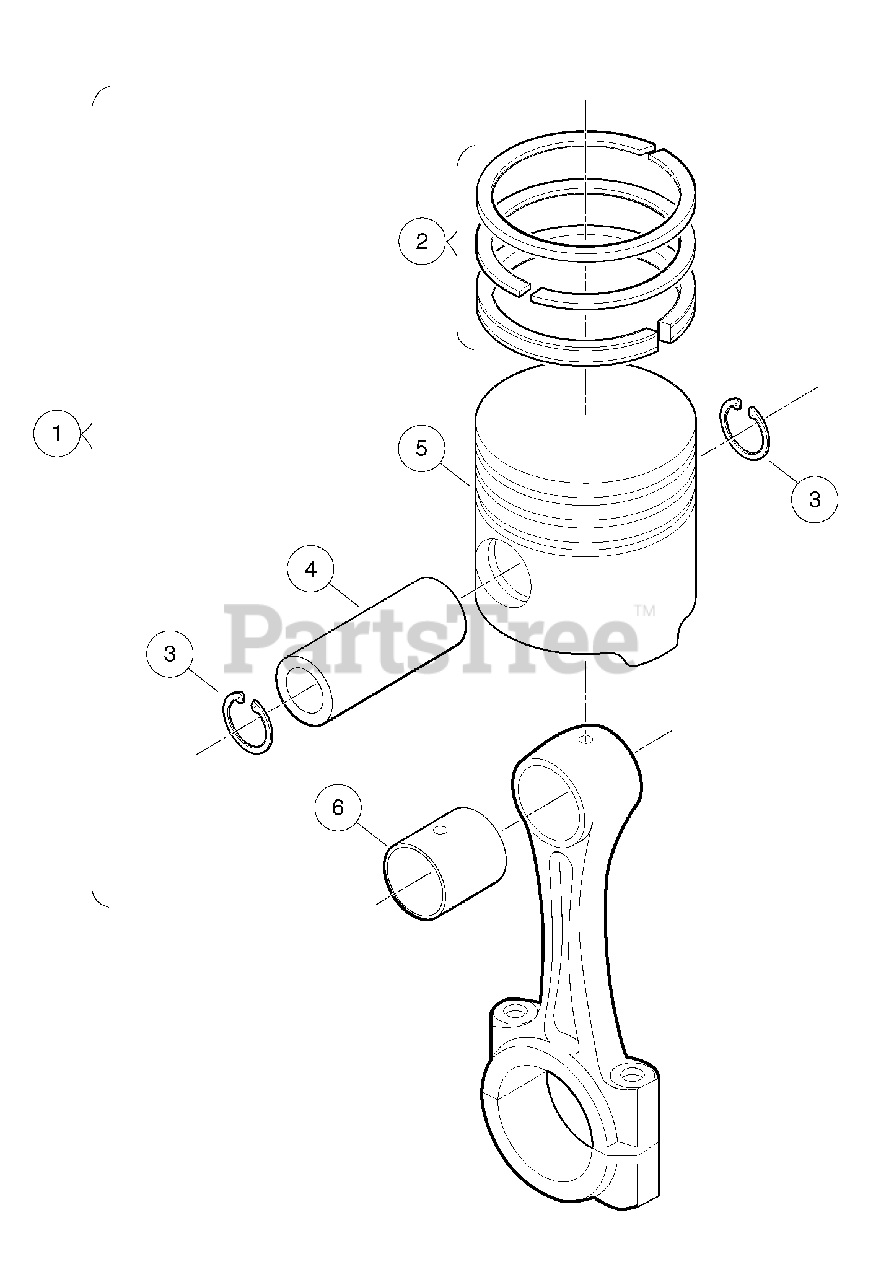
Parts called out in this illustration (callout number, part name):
1	Kit, Piston Rebuild, D722
2	Assy Piston Ring, D722 Std
3	Circlip, Piston Pin
4	Pin, Piston
5	Piston, D722, Std
6	Bushing, Piston Pin, D722
